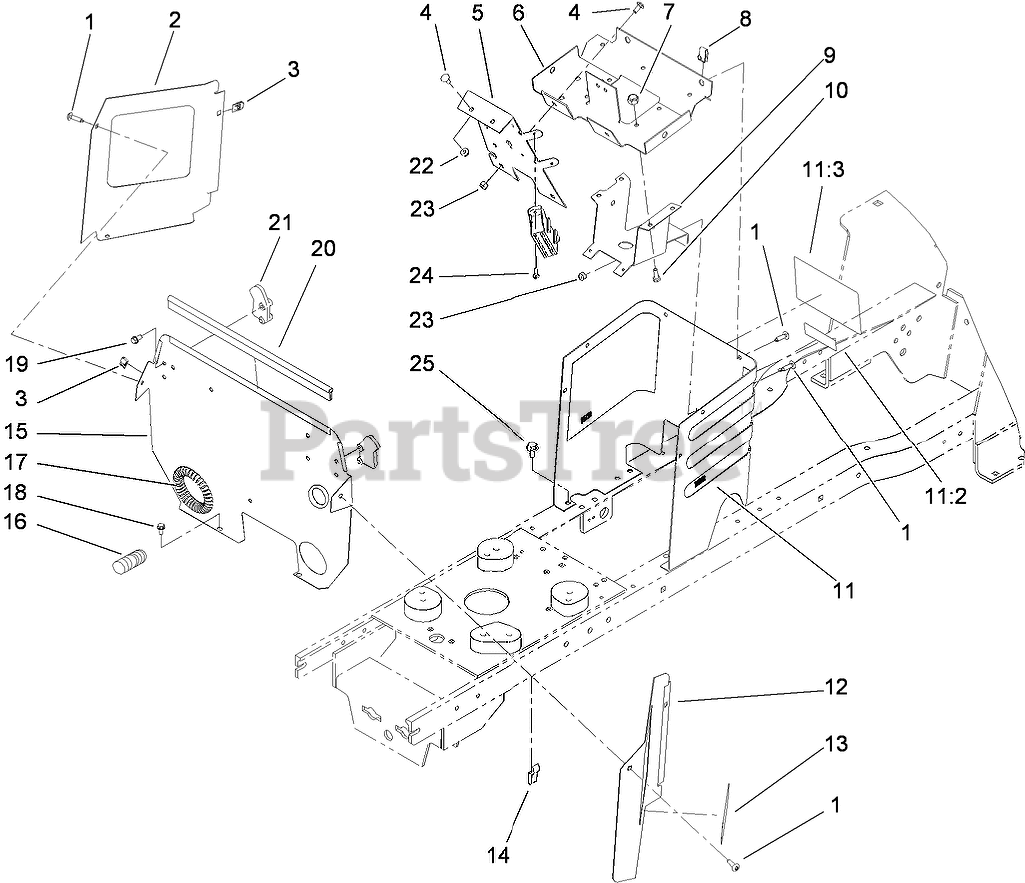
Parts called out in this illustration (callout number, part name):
1	SCREW-HH
2	RH SIDE COVER ASM
4	SCREW-CARR
5	PANEL-SUPPORT, DASH
6	SUPPORT-DASH
7	NUT-HEX
9	BRACKET-COLUMN, LOWER
10	SCREW-HH
11	HOODSTAND W/DECALS ASM
11:2	DECAL-INSTRUCTION
11:3	DECAL-DANGER
12	LH COVER ASM
14	CLAMP-CASING
15	FIREWALL
16	HARNESS-WIRE
17	COVER-SHAFT, DRIVE
18	SCREW-HWH
19	SCREW-PLASTITE
20	TRIM-SEAL, FIREWALL
21	LATCH-HOOD
22	NUT-KEPS
23	NUT-LOCK, NI
24	SCREW-PPHTF
25	SCREW-HWHTF
